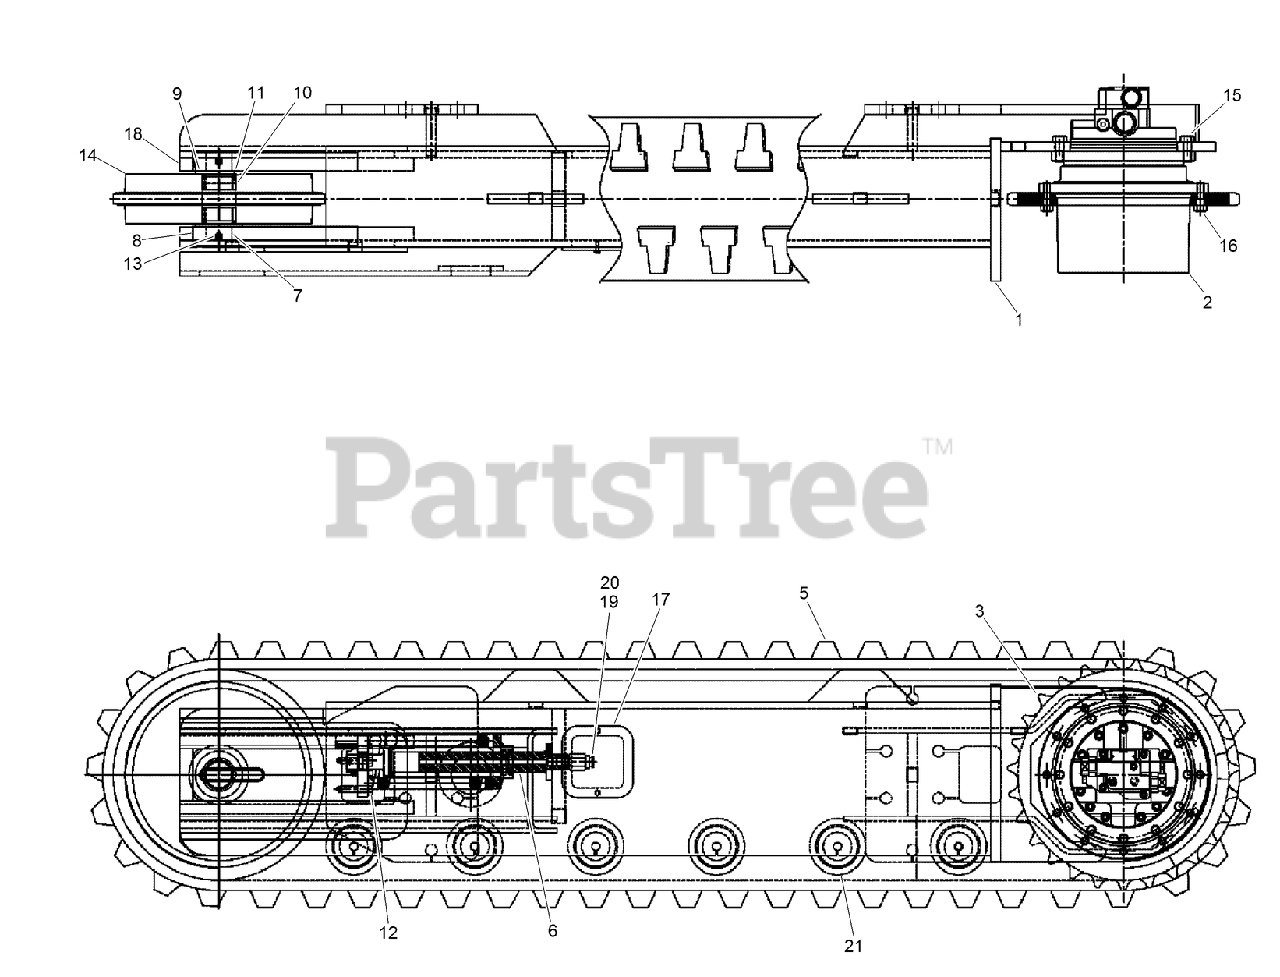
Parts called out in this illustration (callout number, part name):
1	WELDMENT - Track Drive, Right Hand
2	PLANETARY GEARBOX ASM
3	SPROCKET - Drive, Track, 27 Tooth
5	TRACK-RUBBER
6	TENSIONER-TRACK
7	PIN-AXLE
8	SLIDER - Tensioner Bar, 1-1/2 x 4 x 12-11/16 Long
9	BEARING-THRUST
10	BEARING - Roller, without Inner Ring, 2.00 ID x 2.562 OD
11	SEAL-SHAFT
13	PIN-SLOTTED, SPRING
14	SPROCKET - Idler, 16-1/4 OD x 4 Thk
15	SCREW-HH
16	SCREW-HH
17	COVER - Access Opening
18	SLIDER - Tensioner Bar, 1-1/2 x 4 x 12-11/16 Long
19	FITTING - Grease, Giant Button Head
20	WASHER - Copper, Seal.
21	ROLLER-TRACK
